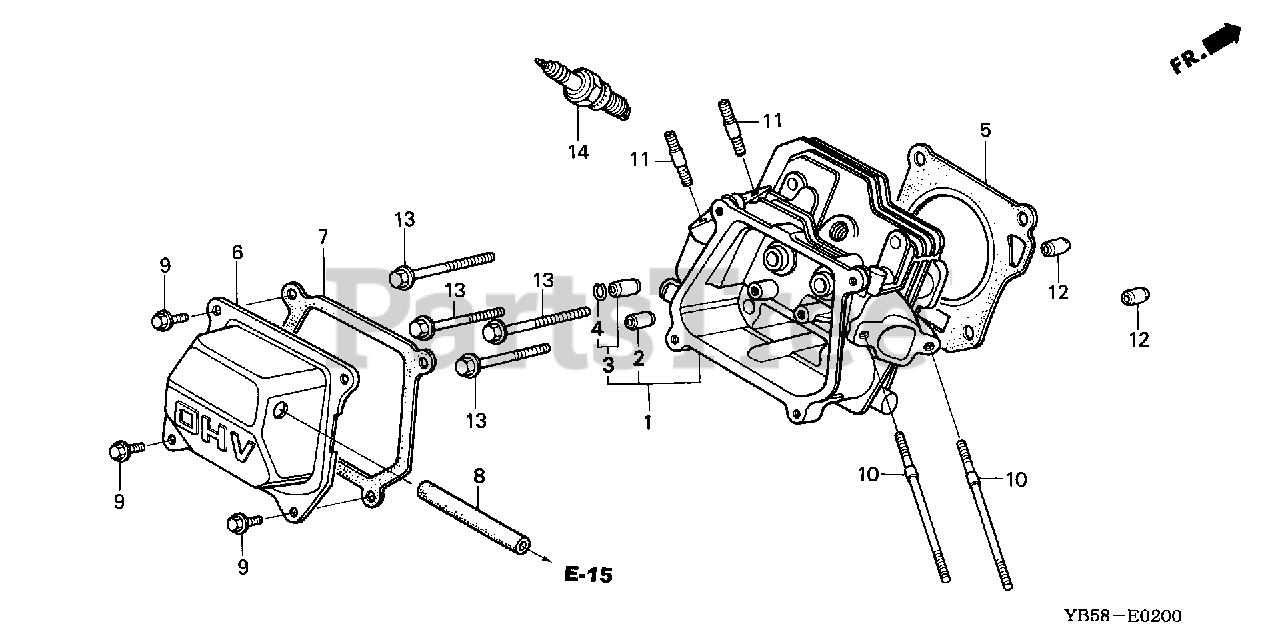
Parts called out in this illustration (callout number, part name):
1	CYLINDER HEAD
2	GUIDE, VALVE (OVER SIZE)
3	GUIDE, EX. VALVE (OVER SIZE)
4	CLIP, VALVE GUIDE
5	GASKET, CYLINDER HEAD
6	COVER, HEAD
7	GASKET, HEAD COVER
8	TUBE, BREATHER
9	BOLT, FLANGE (6X12) (CT200)
10	BOLT, STUD (6X112)
11	BOLT, STUD (8X32)
12	PIN, DOWEL (10X16)
13	BOLT, FLANGE (8X55)
14	SPARK PLUG (BPR6ES) (NGK)
14	SPARK PLUG (W20EPR-U) (DENSO)
